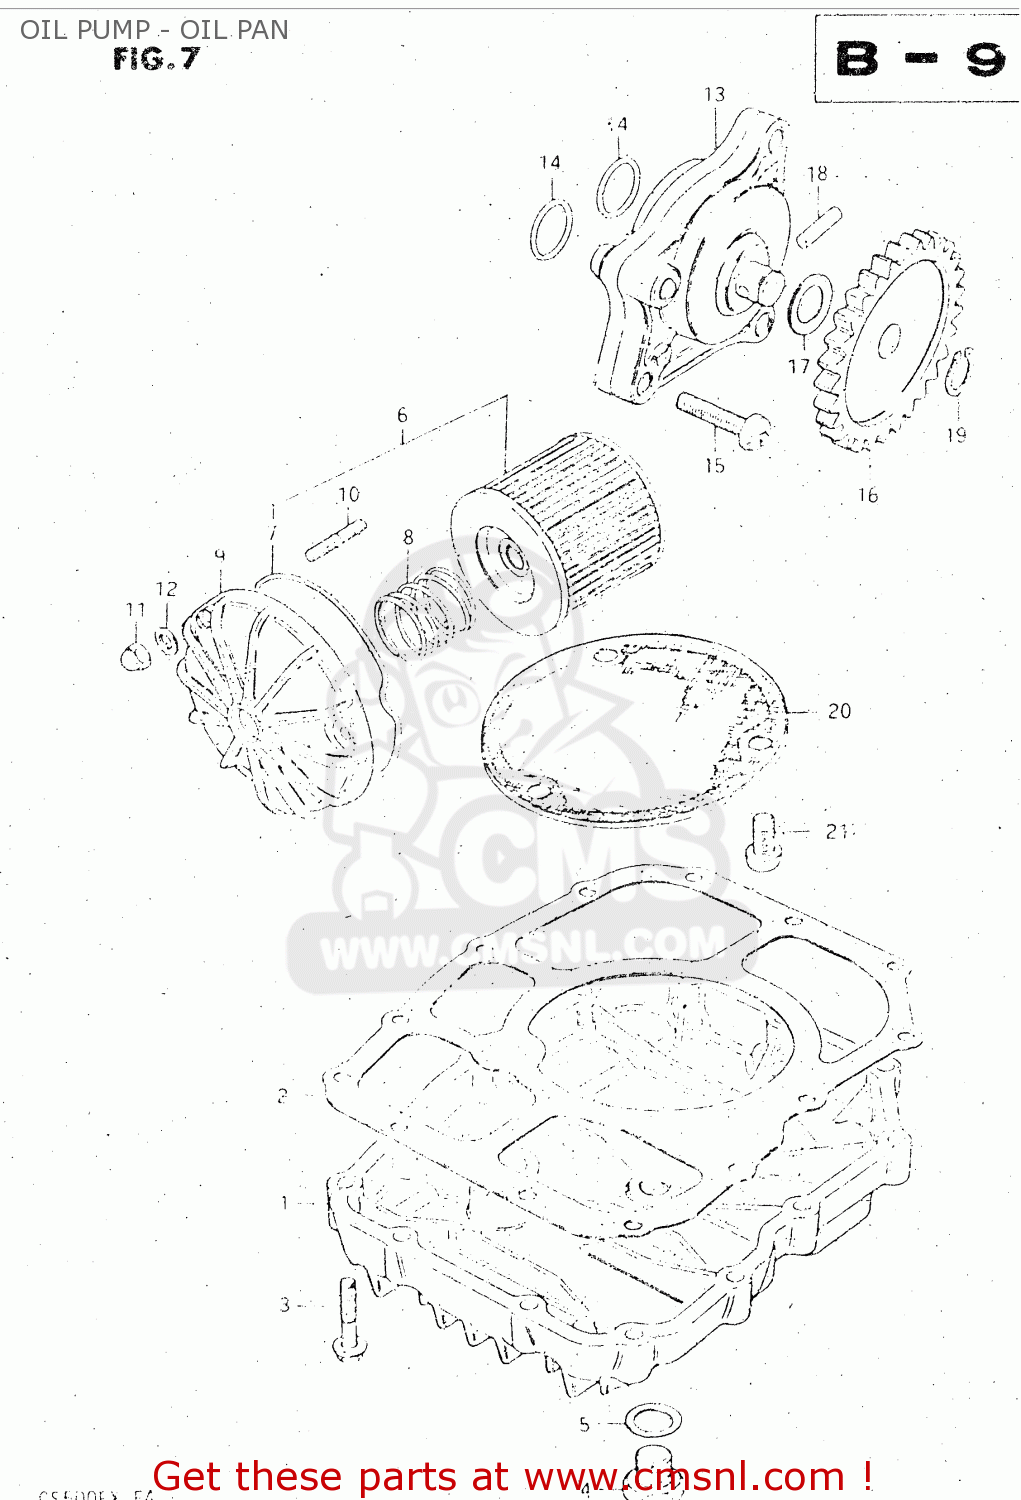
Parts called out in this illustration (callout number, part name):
1	PAN,OIL
2	GASKET,OIL PAN (MCA)
3	BOLT
4	PLUG
5	GASKET(14X19.2X2) (NAS)
6	ENGINE OIL FILTER SET
7	O RING,OIL FILTER CHAMBER CAP
8	SPRING
9	CAP,ENGINE OIL FILTER
10	STUD 6X20
11	NUT
12	WASHER
13	PUMP ASSEMBLY,ENGINE OIL
14	O RING(D:1.9,ID:13)
15	SCREW
16	GEAR,OIL PUMP DRIVEN
17	SHIM
18	PIN(4X15.8)
19	CIRCLIP
20	STRAINER,ENGINE OIL
21	SCREW 6X12
